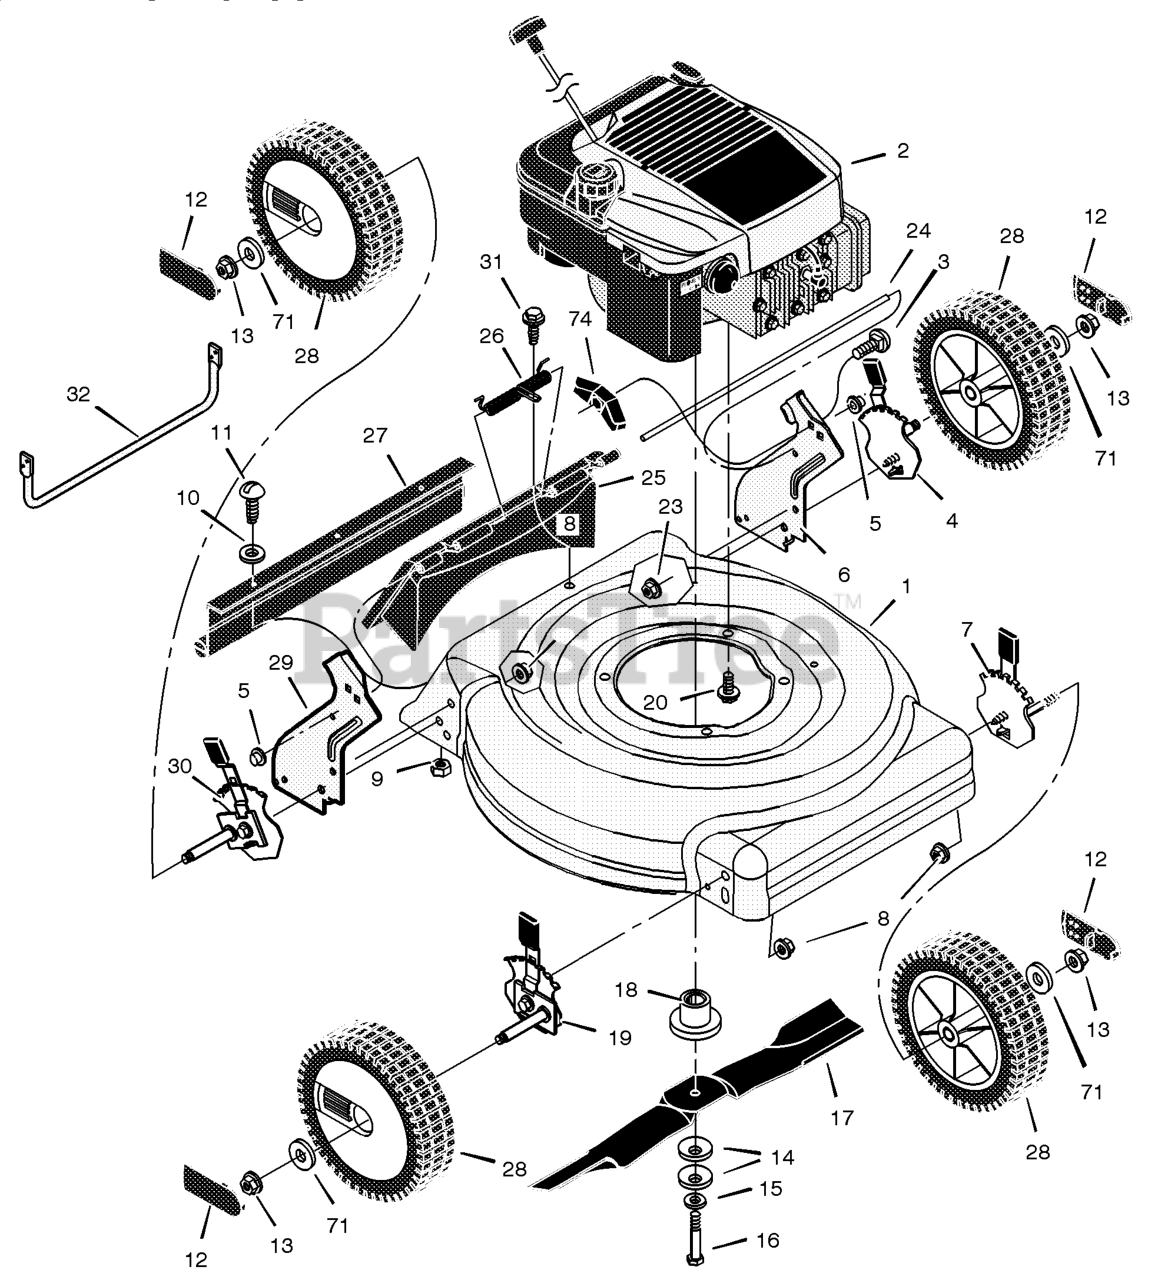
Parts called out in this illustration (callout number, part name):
1	Housing
2	Engine
3	Bolt, Carriage
4	Adjuster, Left Rear Height
5	Push On Cap
6	Bracket, Left Handle
7	Adjuster, Left Front Height
8	Nut, Flange
9	Nut, Hex
12	Hub Cap
13	Nut, Flange
14	Washer, Belleville
18	Adapter, Blade
19	Adjuster, Right Front Height
20	Bolt, Engine
23	Nut, Flange
24	Rod, Pivot
25	Door, Rear
26	Spring
27	Guard, Rear
29	Bracket, Right Handle
30	Adjuster, Right Rear Height
32	Guard, Rear
